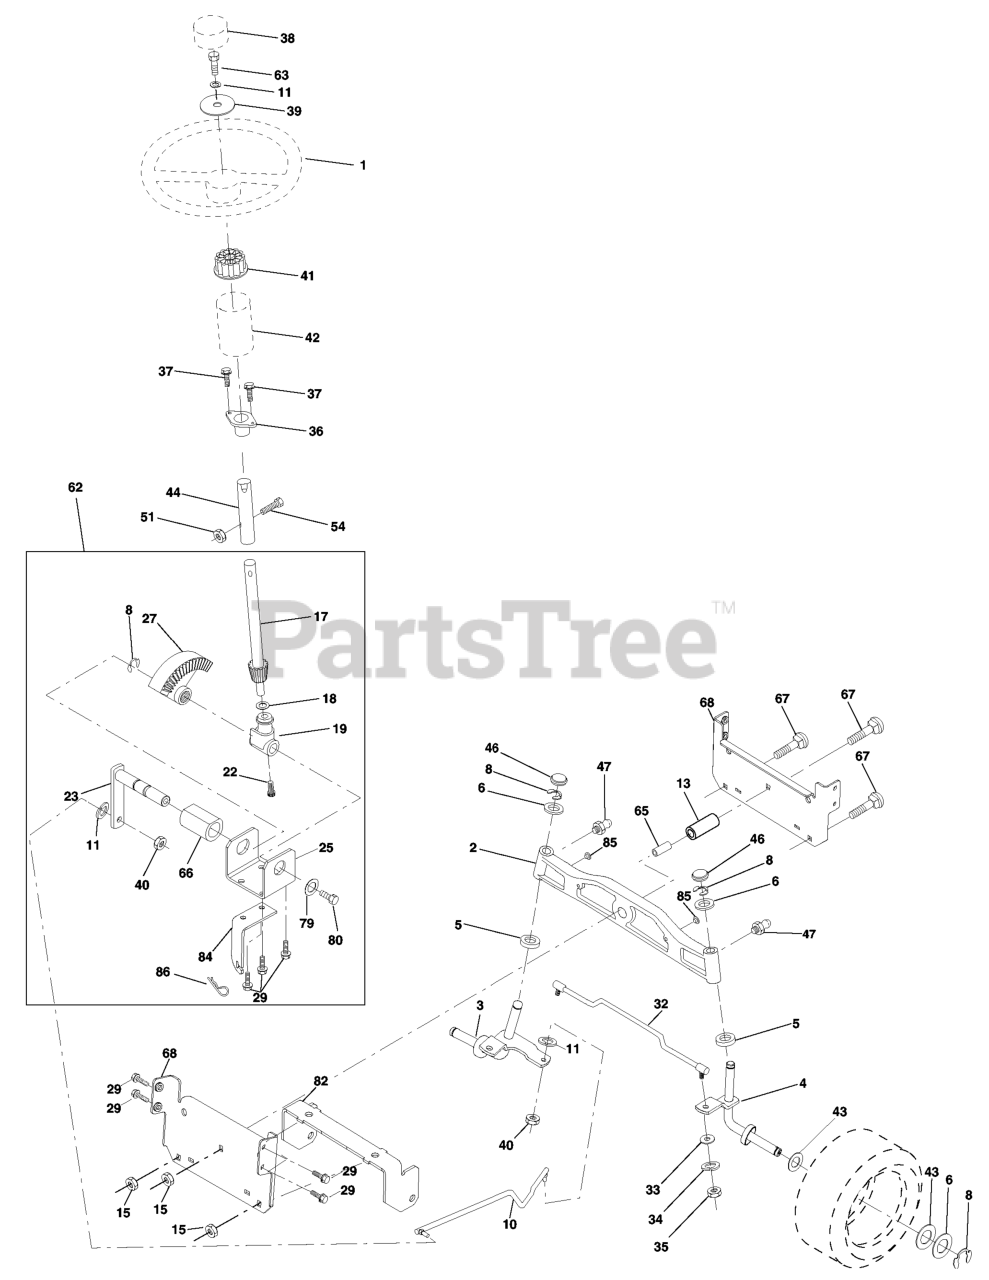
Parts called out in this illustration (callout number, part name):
1	STEERING WHEEL
2	AXLE
3	SPINDLE.ASM.LH.15"TIRES
4	SPINDLE.ASM.RH.15"TIRES
5	THRUST WASHER
10	DRAGLINK.15".TIRES
11	WASHER, LOCK 3/8
13	TUBE, PIVOT AXLE
15	NUT
17	SHAFT ASM STEERING
18	THRUST WASHER
19	STEERING SHAFT SUPPORT
22	SCREW.HX.WSH.HD
23	SHAFT ASSY PITTMAN
25	BRACKET STEERING
27	GEAR.SECTOR
29	SCREW 3/8-16X3/4
32	ROD.ASM.TIE.BALL.JOINT.NOVAN
33	WASHER M
34	WASHER.LOCK.HVY.HLCL.SPR.5/16
35	LOCKNUT
36	BUSHING, STEERING
37	SCREW.TT.#10-32X.5.3/8.FLANGE
38	CAP.WHEEL.STEERING.GREY
39	Washer 13/32 x 1-1/20 x 11 Gauge
40	GRIPCO NUT
41	STEERING WHEEL ADAPTOR
42	BOOT STEERING
44	EXT SHAFT STEERING
46	CAP.SPINDLE.BLACK
47	ZERK M
51	NUT.71038.31-18.HEX.NYLOCK
54	BOLT.5/16-18X1-1/4 FULL.THREAD
62	STEERING KIT
63	BOLT
65	SPACER BRACE AXLE
66	BEARING ARM
67	BOLT
68	BRACE.AXLE.15"TIRES
79	WASHER
80	BOLT.HX.NYLON3/8-16X
82	BRACKET
84	Bracket Cable Clutch Chassis
85	FASTENER.XMAS.TREE
86	SPRING.RETAINER.YELLOW.ZINC
